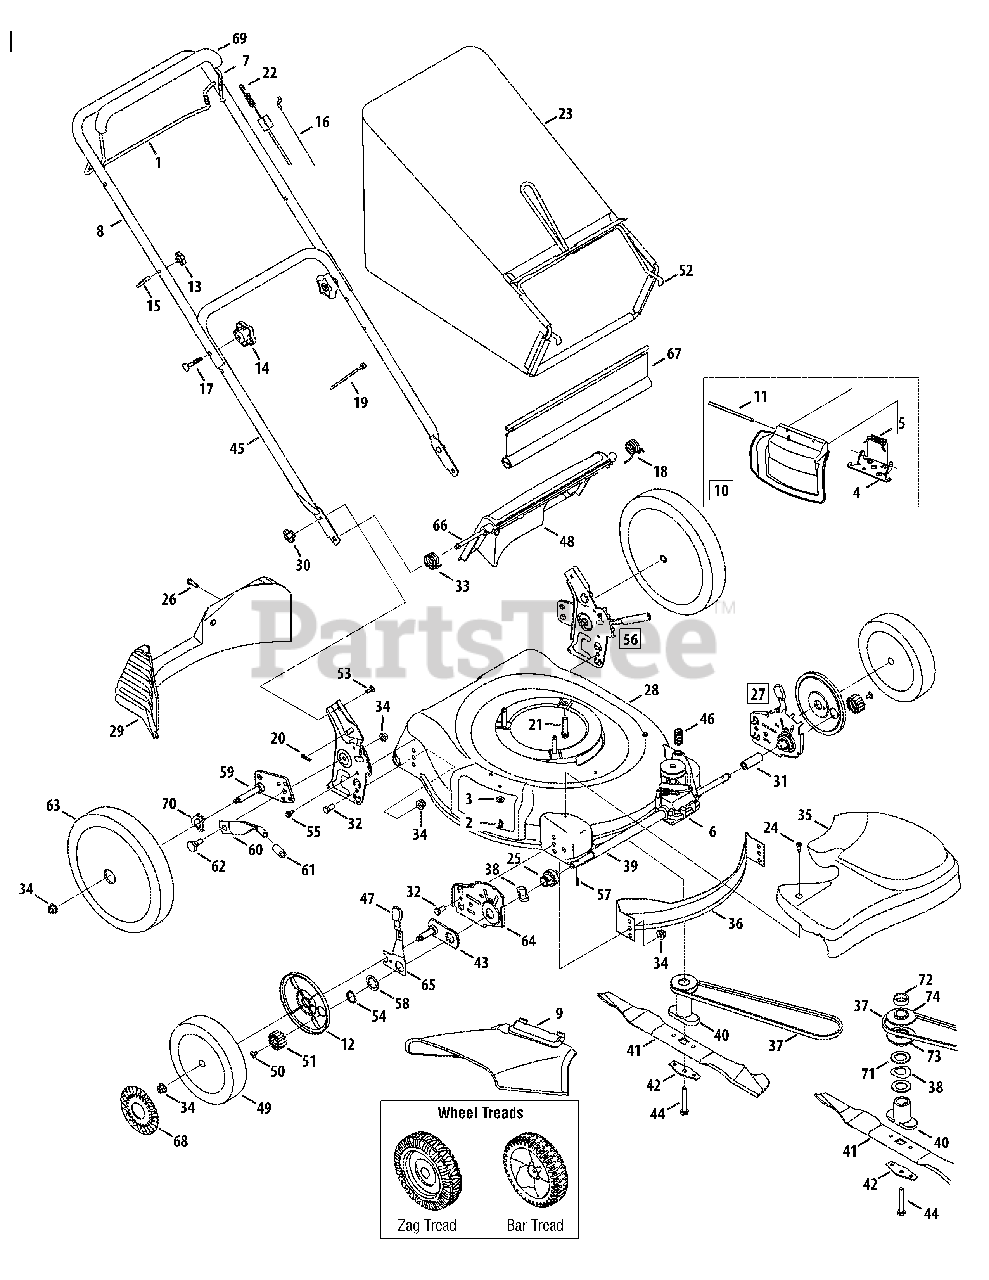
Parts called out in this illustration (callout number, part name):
1	Drive Control
2	TT Screw 1/4-20 x 0.5
3	Bell Washer.265 x 0.75
4	Deflector Chute Adapter
5	Torsion Spring
6	Transmission Assembly
9	Chute Deflector
10	Mulch Plug Complete
11	Hinge Pin
12	Wheel Dust Cap
13	Handle Knob
14	Star Knob
15	Eye Bolt
16	Control Cable - 37.750"
17	Carriage Bolt 5/16-18 x 2.0
18	Torsion Spring - LH
19	Cable Tie
20	Cotter Pin
21	Self-Tapping Sems Screw
22	Drive Cable - 51"
23	Grassbag Assembly - Yardman
23	Grassbag Assembly - Black
24	Shoulder Screw # 12 -24
25	Front Bearing Assembly
26	Screw, 1/4-15 x 1.000
27	Height Adjustment Ass’y - RH
27	Height Adjustment Ass’y - LH
30	Wing Nut
31	Slev. Spacer 1.4" Lg.
32	Hex Screw, 3/8-16 x.75
33	Torsion Spring - RH
34	Flange Lock Nut, 3/8-16
35	Transmission Cover - Black
35	Transmission Cover - Yellow
36	Front Baffle
37	V-Belt
38	Wave Washer
39	Sleeve Spacer 8.985" Lg.
40	Blade Adapter, 25mm
41	21" Mulching Blade
42	Blade Bell Support
43	Pivot Plate Assembly
44	Hex Screw 3/8-24 x 2.50
46	Belt Tension Spring
47	Adjustment Knob
48	Rear Discharge Door
49	Front Wheel, 8 x 1.8, Bar, Gray
49	Front Wheel, 8 x 1.8, Bar, Yellow
49	Front Wheel, 8 x 2.125, Zag
50	Screw, 1/4-20 x .390
51	Gear 14T RH FWD
51	Gear 14T LH FWD
53	Carriage Bolt 1/4-20
54	Snap Ring
55	TT Scr. w/Washer 1/4-20 x.625
56	Handle Bracket Assembly - LH
56	Handle Bracket Assembly - RH
57	Dowel Pin
58	Washer
59	Pivot Arm Assembly - RH
59	Pivot Arm Assembly - LH
60	Rear Spring Lever
61	Foam Grip
62	Shoulder Scr.500 Dia. x.434
63	Rear Wheel, 12 x 1.8, Bar, Gray
63	Rear Wheel, 12 x 1.8, Bar, Yellow
63	Rear Wheel, 12 x 2.125, Zag
64	Height Adjuster Plate - RH
64	Height Adjuster Plate - LH
65	Front Lever - RH
65	Front Lever - LH
66	Pivot Rod
67	Rear Trailing Shield
68	Hub Cap
69	Deluxe Bail Cover
70	Washer, Sprg, .500 x 1.00 x .022
71	Washer, Flat, 1.031 x 1.620 x .095
72	Spcr., Slev., 25mm x 1.375 x .620
73	Pulley, Half
74	Pulley, Half
